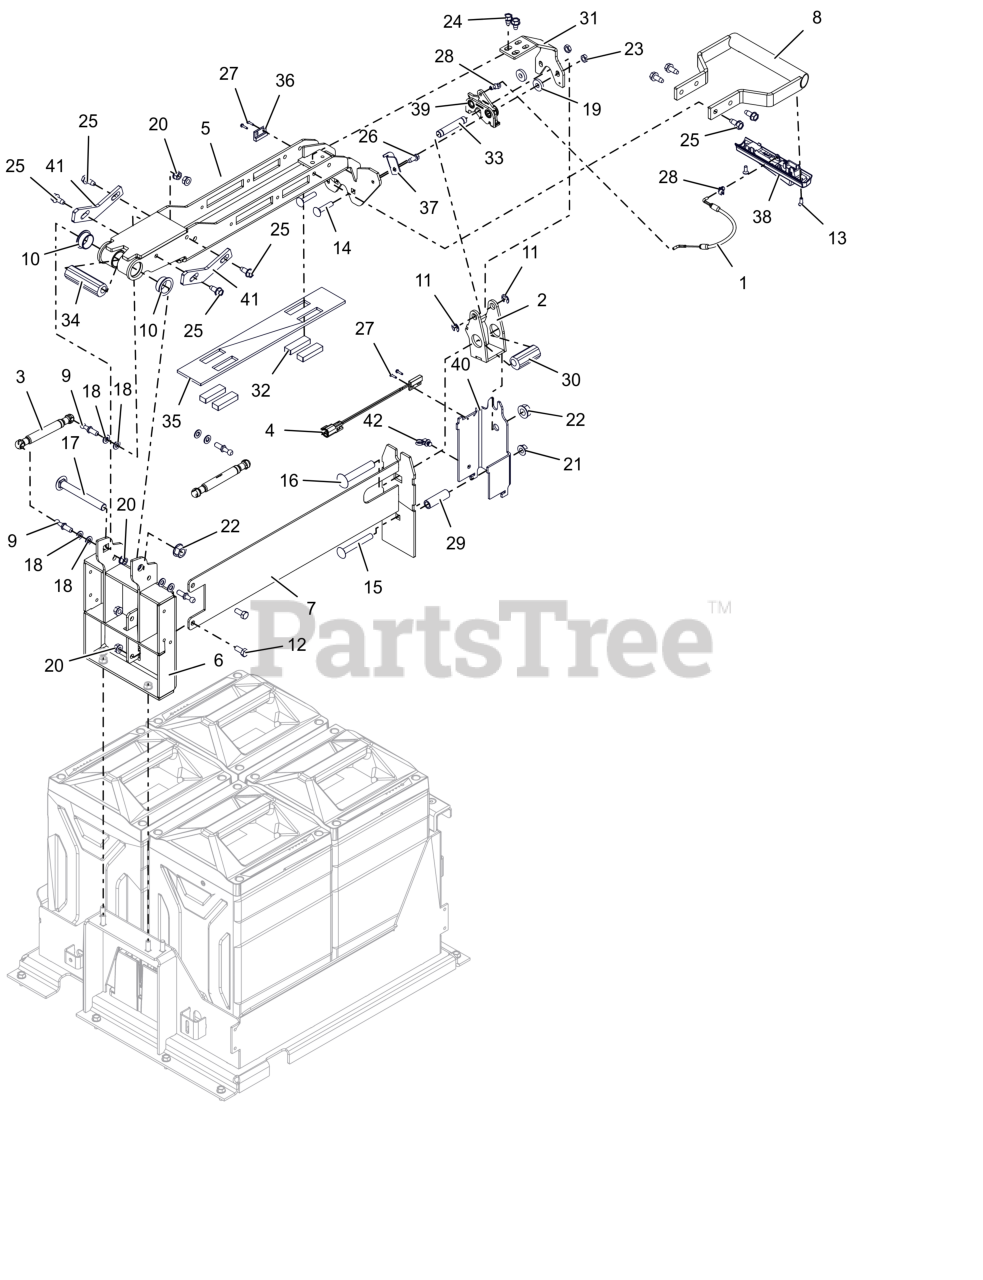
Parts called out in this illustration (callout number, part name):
1	CABLE, HOOD RELEASE
2	WLDMT, ECCENTRIC
3	DAMPER, GAS
4	SWITCH, MAGNETIC
5	WLDMT- HOLDOWN MAIN
6	WLDMT- PIVOT BATTERY HOLDDOWN
7	WLDMT- ECCENTRIC MTG
8	WLDMT, HANDLE (ORANGE)
9	STUD-BALL-THREADED
10	BSHG-FLG 1.0X1.125X.50X1.375 R
11	RG-RTNG-EXT .438X.035
12	BLT,HEX .31-18X.75 G5 ZCC
13	SCR, FLCSKH M5-0.8X14 GR10.9 ROHS
14	BLT,RHSN .31-18X1.50 G5 ZCC
15	BTL,RHSSN .375-16 X 3 G5 ZCC
16	BTL,RHSSN .500-13 X 3 G5 ZCC
17	BTL,RHSSN .500-13 X 4.25 G5 ZCC
18	WSHR,FLT .323X.625X.062 ZCC
19	WSHR, FLT .328X.870X.179 ZCC
20	NUT,LK-CTR-FLG .31-18 GF ZCC
21	NUT-LK-CTR-FLG .375-16 GF ZCC
22	NUT-LK-CTR-FLG .500-13 GG ZCC
23	NUT-LK-CTR-JAM .312-18 GB ZCC
24	SCR,TAP .312-18X.50 HWH TR ZCC
25	SCR,TAP .312-18X.75 HWH TR ZCC
26	SCR,TAP .25-20X.625 HWH ZCC
27	SCR-TAP #4-40x.50 HWH ZCC
28	CLIP, RETAINER
29	SPCR, LATCH BRKT (BLACK)
30	ECCENTRIC, HOOD LATCH
31	BRKT, LATCH MTG (ORANGE)
32	PAD, RUBBER
33	ROD, LATCHING
34	ECCENTRIC, HOOD LATCH-FRONT
35	PAD, RUBBER
36	SWITCH, MAGNET (NO WIRE)
37	RETAINER, CABLE (BLACK)
38	HANDLE, SQUEEZE ACTUATOR
39	LATCH, PUSH TO CLOSE
40	BRKT, ECCENTRIC MTG (ORANGE)
41	STOP, HOOD (BLACK)
42	CABLE TIE W/ TREE (.25 HOLE)
